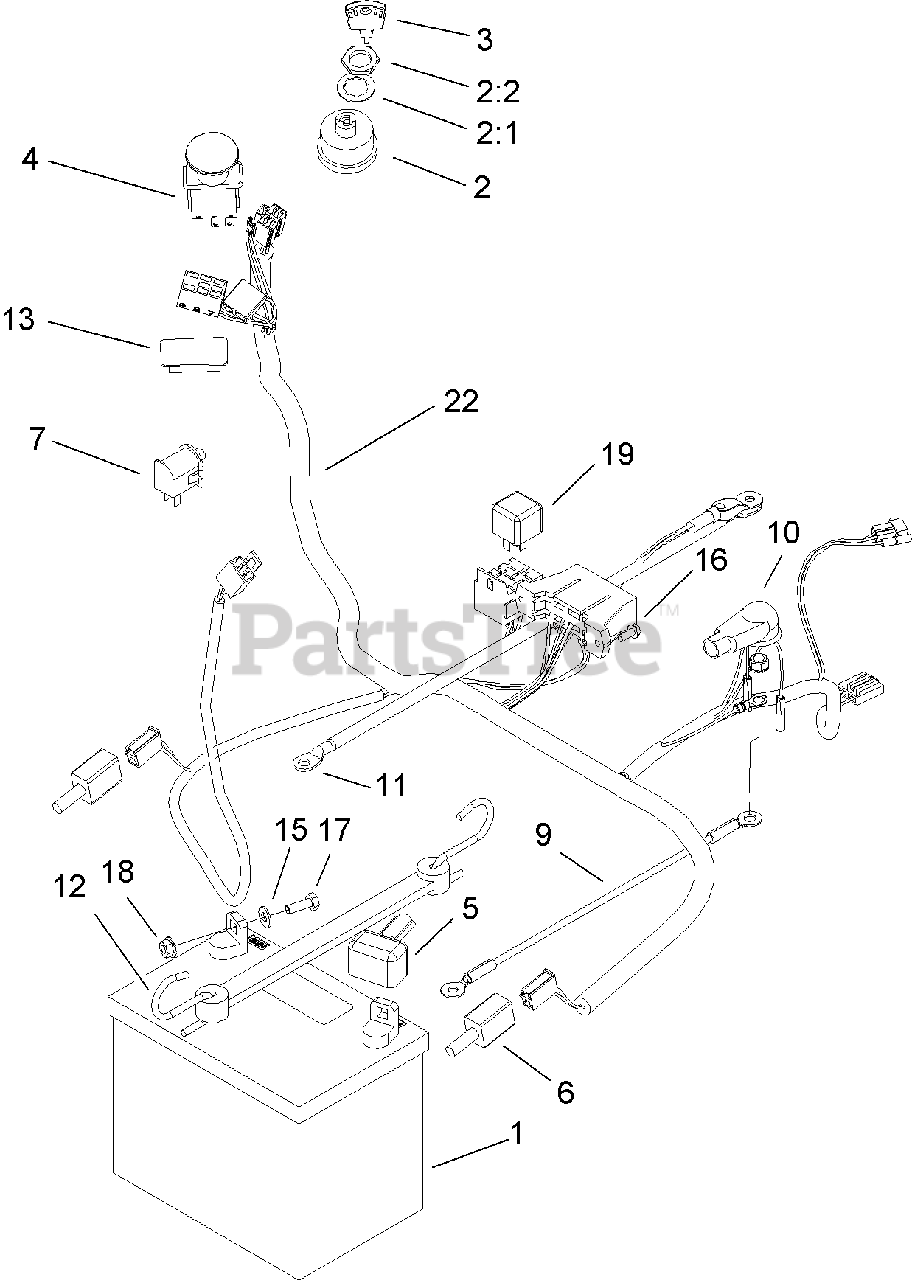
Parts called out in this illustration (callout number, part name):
1	BATTERY-DRY
2	Key Switch ASM
2:1	WASHER-TOOTH
4	SWITCH-PTO
5	BOOT-TERMINAL
7	SWITCH-BAIL
9	WIRE ASM
10	BOOT-INSULATOR, TERMINAL
12	HOLDDOWN-BATTERY
15	WASHER-FLAT
16	SCREW-TAPTITE
17	SCREW-HH
22	HARNESS-WIRE W/LIGHTS
